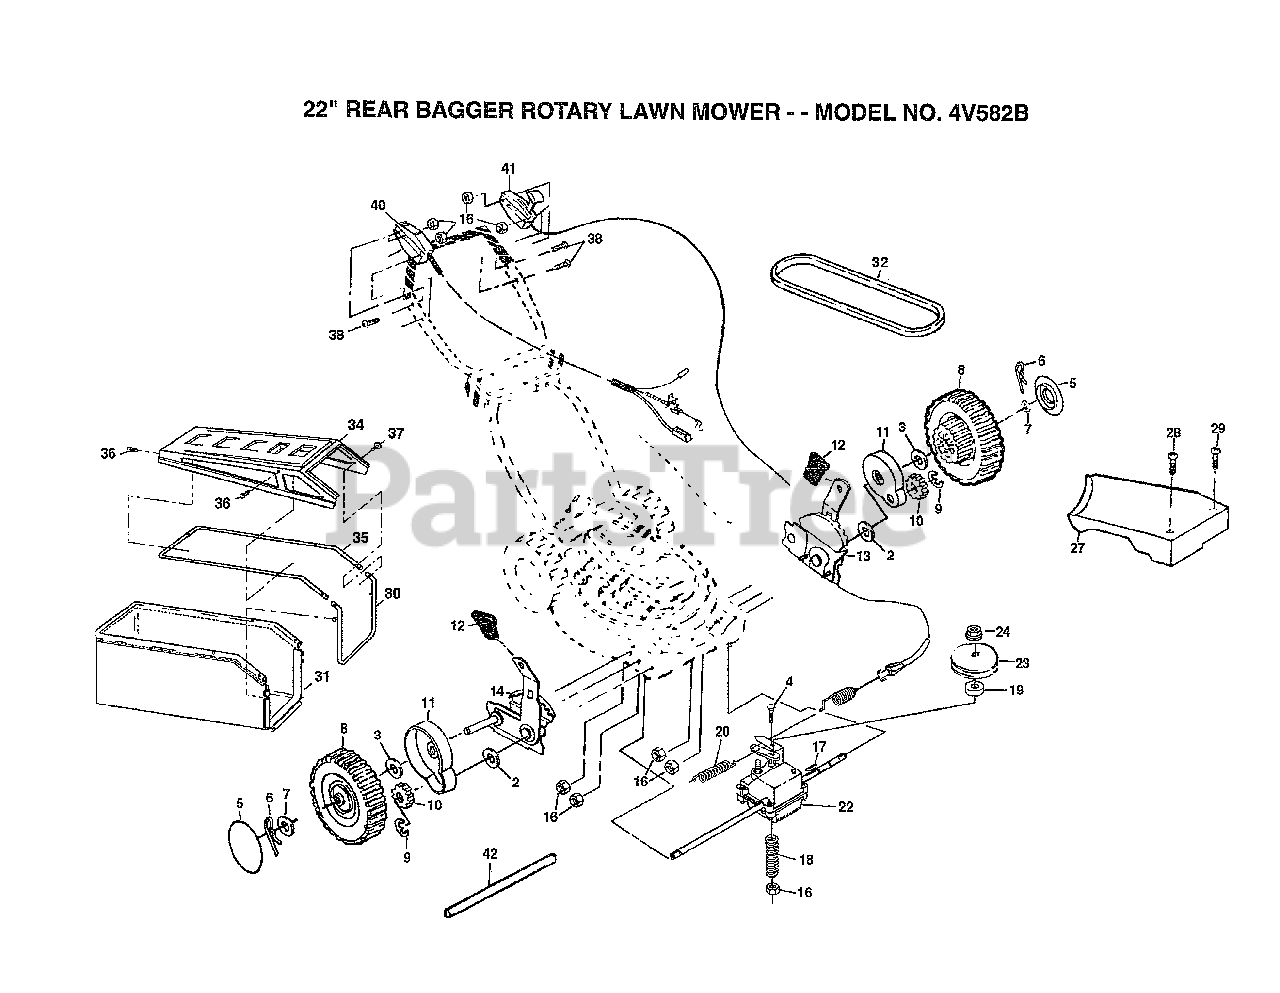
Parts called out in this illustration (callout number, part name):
2	WASHER PM
3	WASHER FLUT
4	BOLT.1/4-20X2.0
5	HUB CAP
6	RETAINER CLIP PM
7	WASHER
8	WHEEL.8X2.LP.PR
10	PINION.GEAR
11	DUST SHROUD PM
12	KNOB PM
17	HI PRO KEY
18	SPRING.TENSION
19	BEARING
20	SPRING
23	PULLEY.DRIVEN
24	LOCKNUT
27	"COVER.DRIVE 22""RD"
30	"FRAME,CATCHER"
34	"TOP,CATCHER"
35	"TUBE,CATCHER"
37	SCREW
41	CONTROL.DRIVE
42	DRV SHAFT TUBE PM
